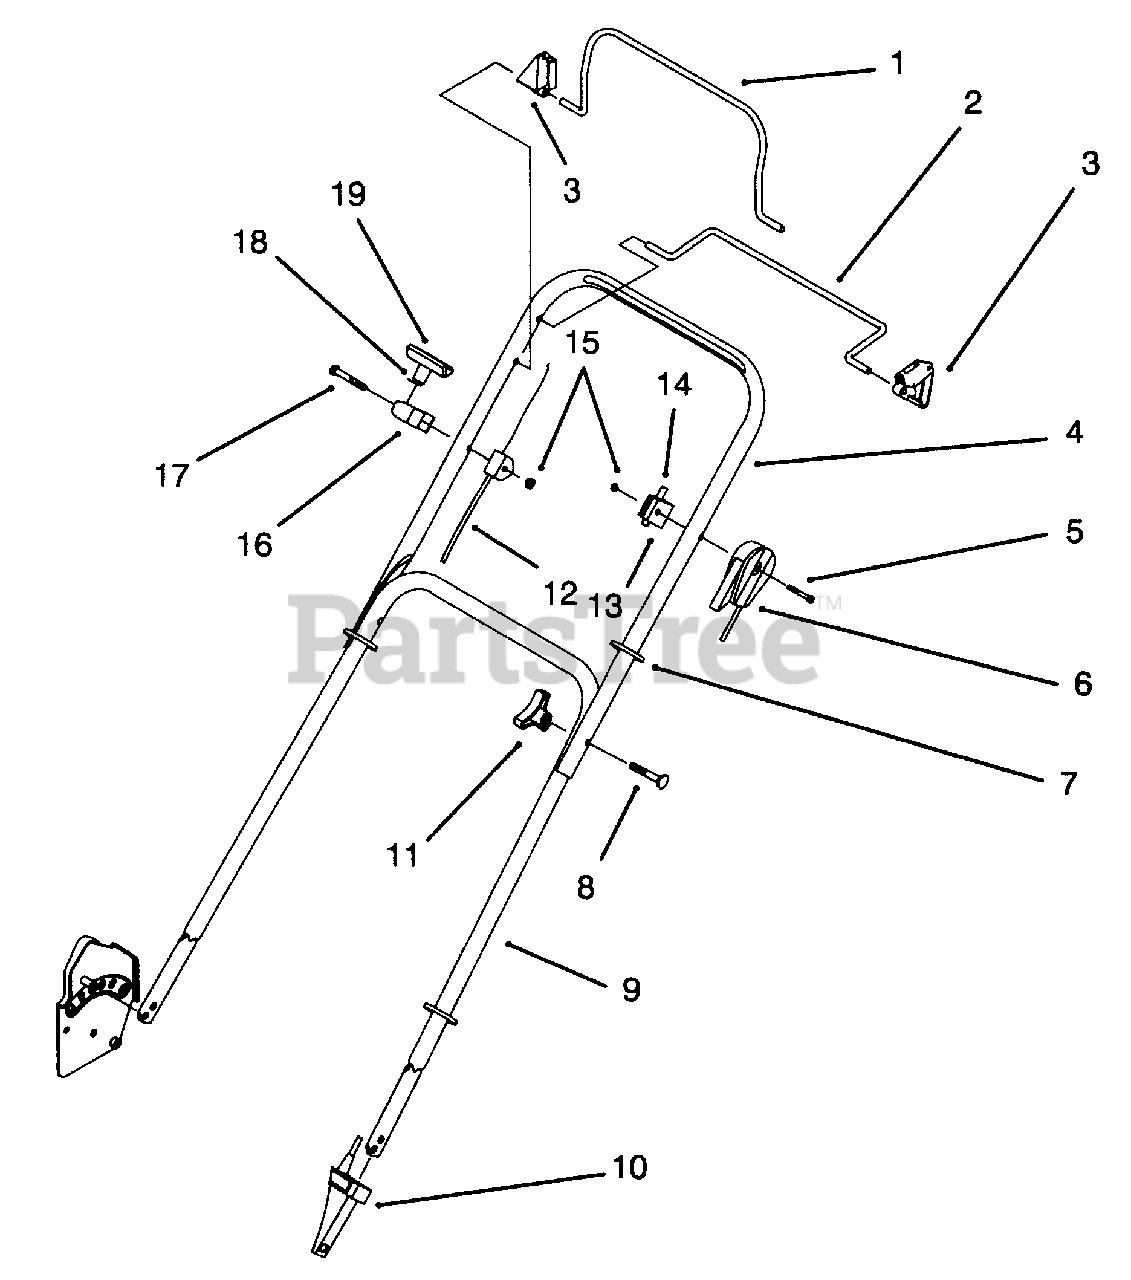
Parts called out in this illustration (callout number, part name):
1	Bail-Flywheel Brake
2	Bail-S.P Control
3	Stop-Pivot
4	Handle-Section Upper
5	Screw-Hex Hd. Cap
6	Cable-Throttle
7	Tie-Cable
8	Screw-Handle
9	Handle-Lower
10	Anchor-Cable Lower
11	Knob
12	Cable-Flywheel Brake
13	Anchor-Cable Upper
14	Cable-Traction
15	Nut-Lock
16	Guide-Rope
17	Screw-Hex Hd. Cap
18	Handle-Starter
19	Clip-Rope Insert
